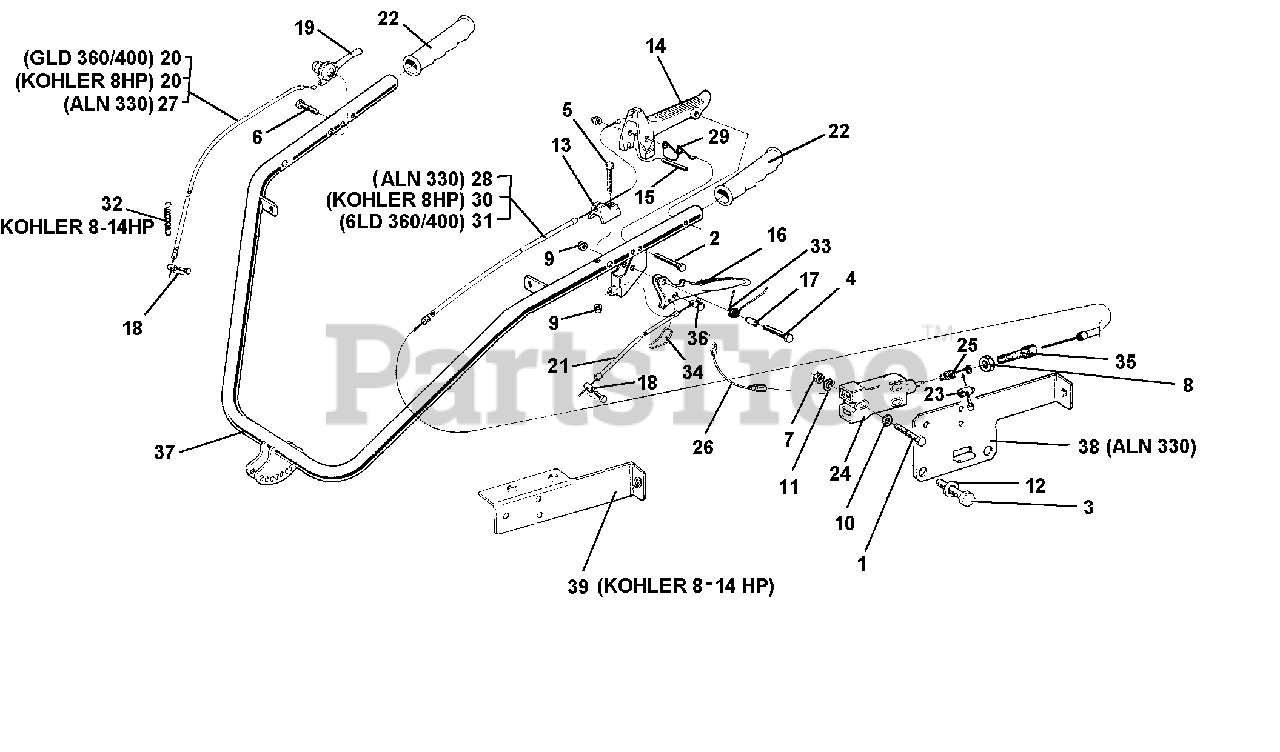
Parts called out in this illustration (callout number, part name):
1	SCREW TE M4 X 25
2	SCREW TE M6 X 45
3	SCREW TE M8 X 12
4	SCREW M6 X 25
5	SCREW M6 X 25
6	SCREW M6 X 40
9	NUT, SELF LOCKING M6
10	FLAT WASHER 4.3
11	LOCK WASHER B 4.3
12	WASHER, LOCK 8.4
13	SHEATH STOP OF MOTOR STOP
14	MOTOR STOP LEVER
15	LEVER STOP FOR MOTOR STOP
16	CLUTCH LEVER
17	LEVER SPACER
18	CLAMP, CABLE
19	LEVER, ACCELERATOR
20	GAS WIRE AND SHEATH
21	CABLE & SHEATH, CLUTCH
23	CABLE CLAMP
24	STOP SWITCH
25	SWITCH SPRING
26	SWITCH CABLES
27	WIRE, SHEATH 1850 GAS
28	SHEATH CABLE
29	MOTOR STOP LEVER SPRING
30	SHEATH CABLE
31	SHEATH CABLE
32	KOHLER GAS CONTROL
33	LEVER SPRING
35	ADJUSTING SCREW
38	SUPPORT FOR ACME STOP SWITCH
39	KOHLER STOP SWITCH SUPPORT
